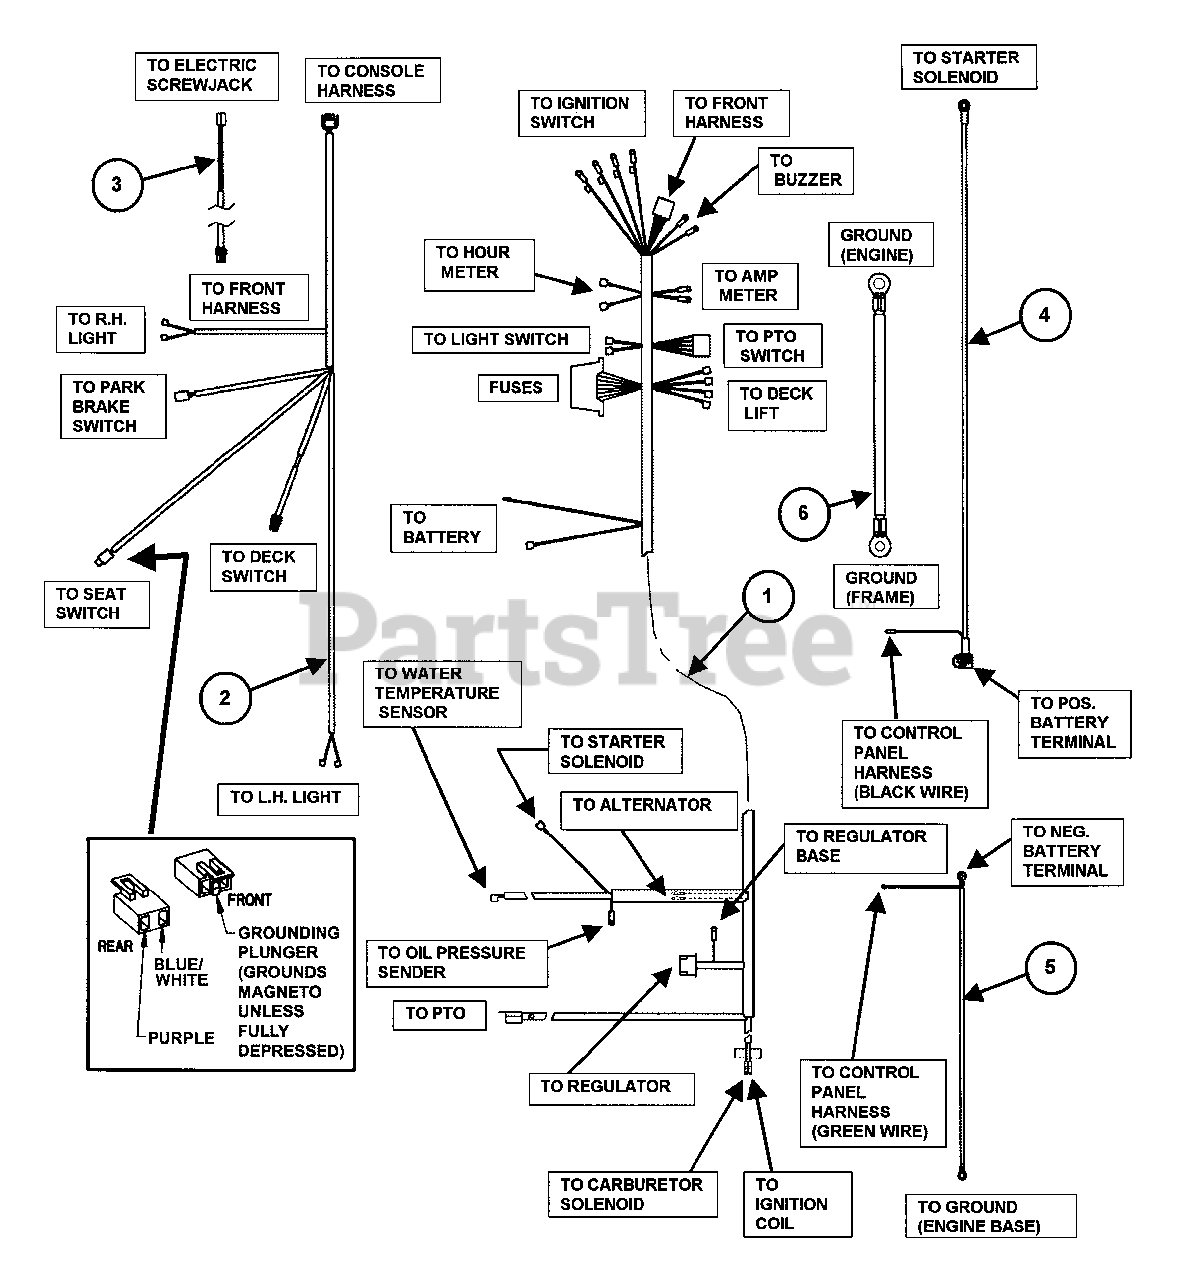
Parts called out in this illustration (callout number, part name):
1	HARNESS, Control Panel
2	HARNESS, Front
3	HARNESS, Deck Lift (15" Long)
4	CABLE, Battery- Positive (51" Long)
5	CABLE, Battery- Ground (38" Long)
6	CABLE, Chassis- Ground (18" Long)
